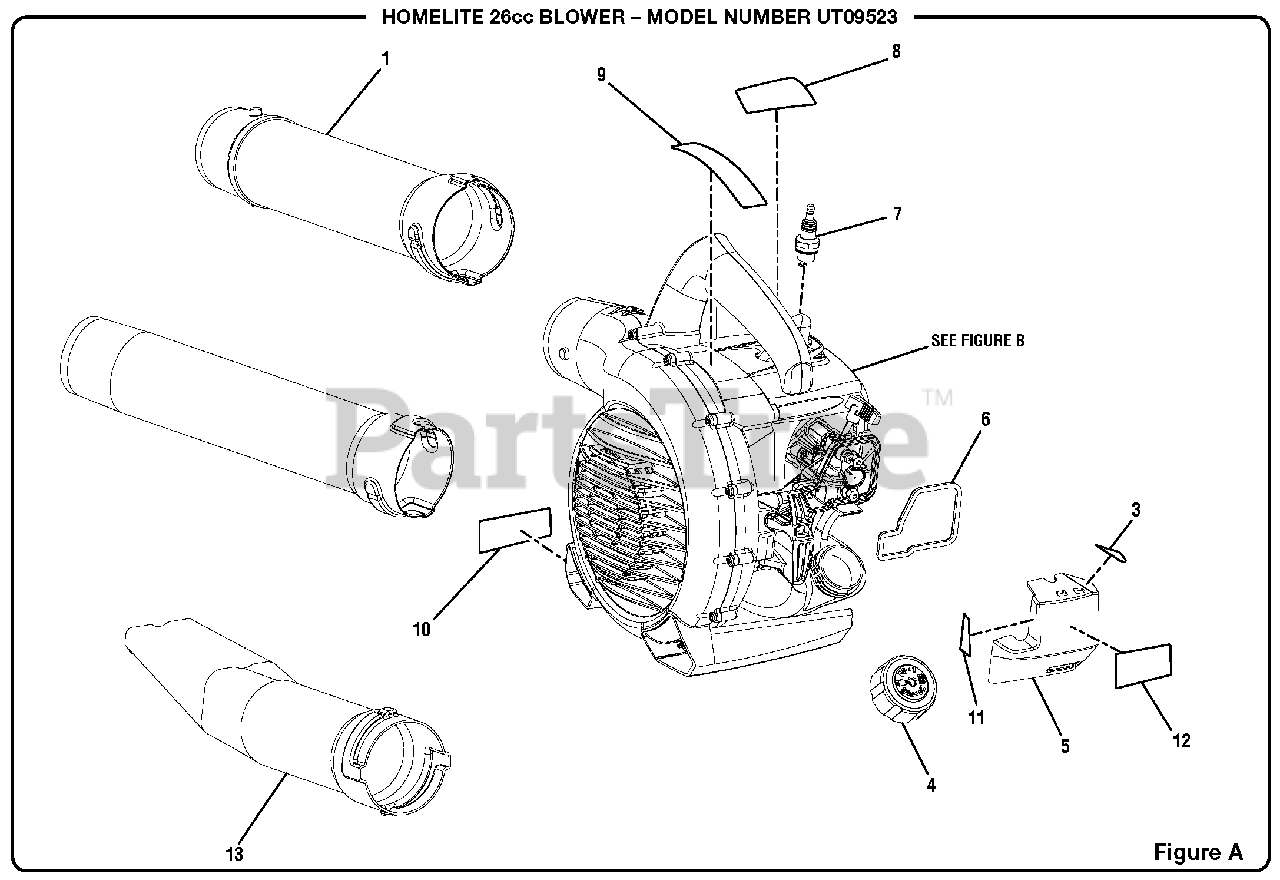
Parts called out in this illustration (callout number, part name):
1	Upper Blower Tube
2	Sweeper Nozzle
3	Throttle Label
4	Fuel Cap Assembly
5	Air Box Cover
6	Air Box Gasket
7	Spark Plug (RCJ6Y)
8	Engine Shroud Label
9	Warning Label
10	Combustion Warning Label
11	Choke Label
12	Starting Instructions Label
13	High Velocity Nozzle w/Leaf Scraper
